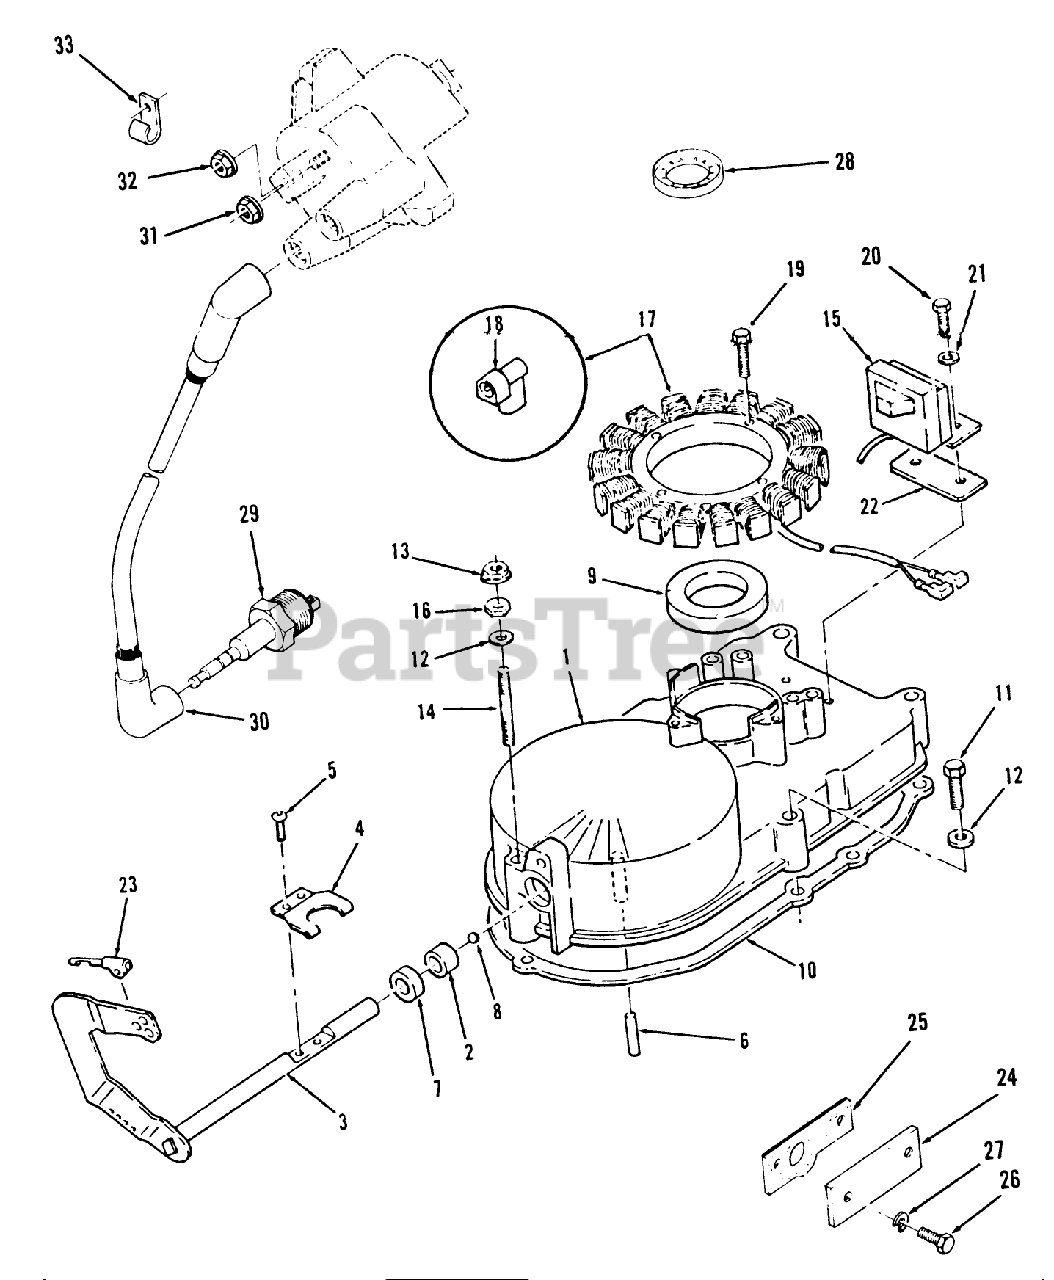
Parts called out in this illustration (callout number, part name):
1	GEAR-CASE KIT
5	SCREW-PAN HD
12	WASHER
17	Stator w/Terminals
24	Plate
25	GASKET
29	SPARK PLUG
